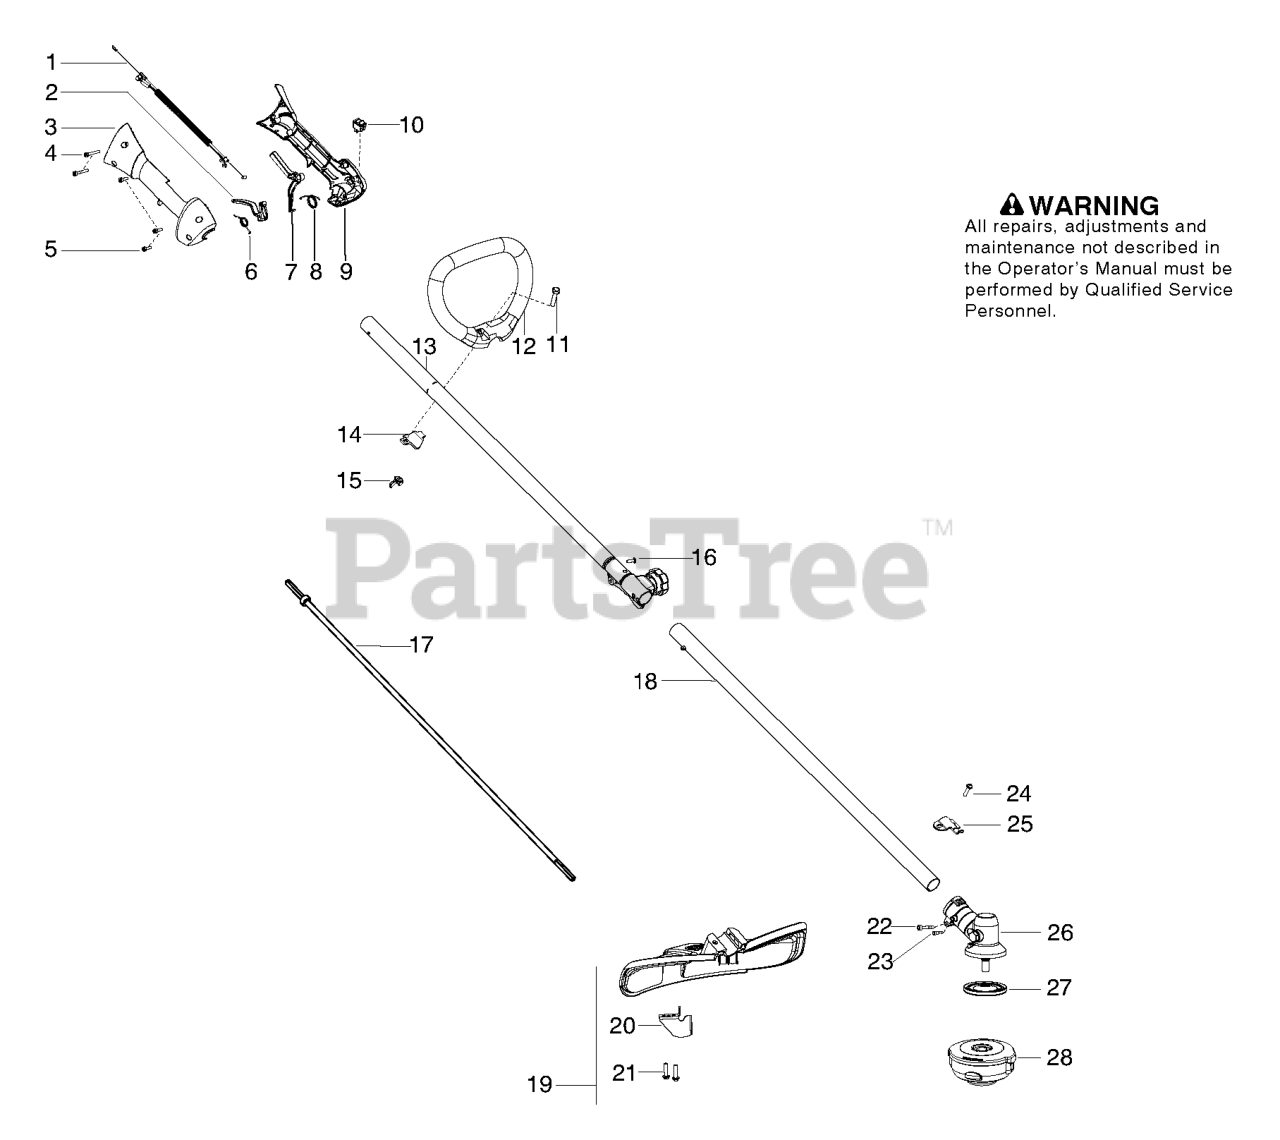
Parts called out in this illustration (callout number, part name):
1	%ASSY CABLE WIRE HARNESS
2	TRIGGER
3	THROTTLE HSG RH
5	SCREW M4 X 1.75 PT 16MM
6	SPRING TRIGGER
7	THROTTLE LOCKOUT
8	SPRING LOCKOUT
9	THROTTLE HSG LH
10	KIT SWITCH
11	BOLT, TYPE 2
12	HANDLE ASSIST
13	KIT-DRIVESHAFT UPPER INC DECAL
14	CLAMP ASSIST HANDLE
15	WINGNUT, TYPE 2
17	FLEX-LOWER
18	HSG DRIVESHAFT LOWER
19	KIT COBI SHIELD
20	Limiter-Line
22	SCREW - CARB. ADAPTOR
24	SCREW 1/4-20 X 7/8 (TAP
25	BRACKET SHIELD STRAIGHT SHAFT
26	ASSY GEARBOX
27	ASSY DUST CUP
28	T25 10MM LH TRIMMER HEAD
